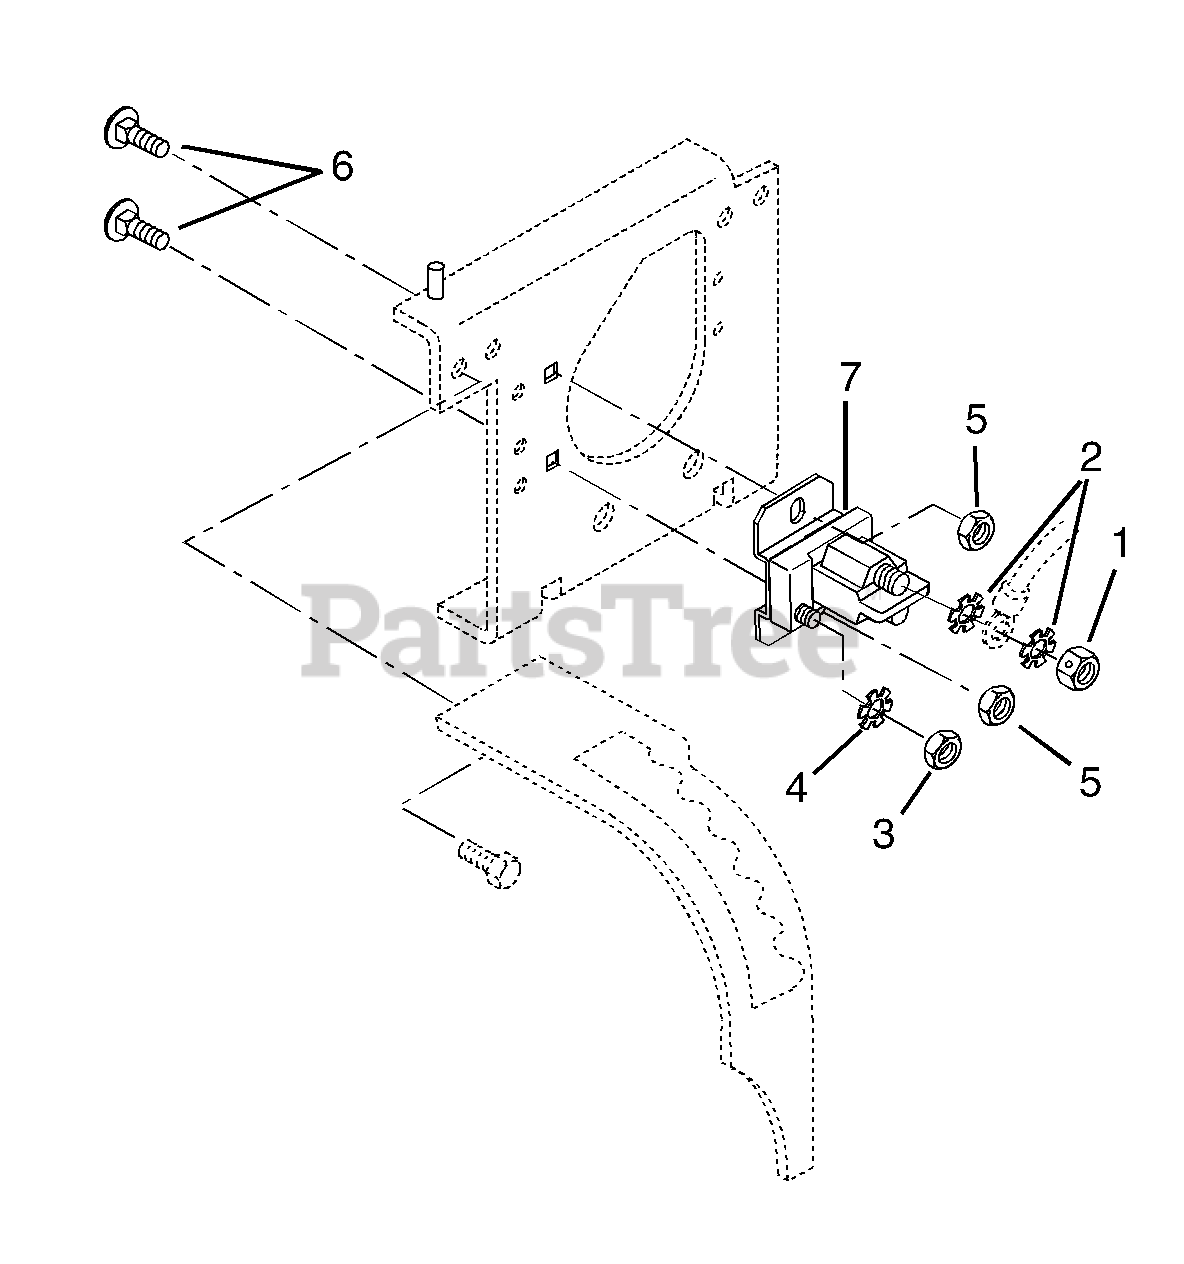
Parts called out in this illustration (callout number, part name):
1	NUT-JAM .31-24 YWZC
2	@WSHR-LK-EXT.262X.502X.026YWZC
3	NUT 10-32 YWZC
4	@WSHR-LK-EXT.200X.402X.022YWZC
5	@NUT-LK-NYL .250-20 YWZC
6	@BLT-RDHDSQNK .25-20X.50 G5YZ
7	SOLENOID
